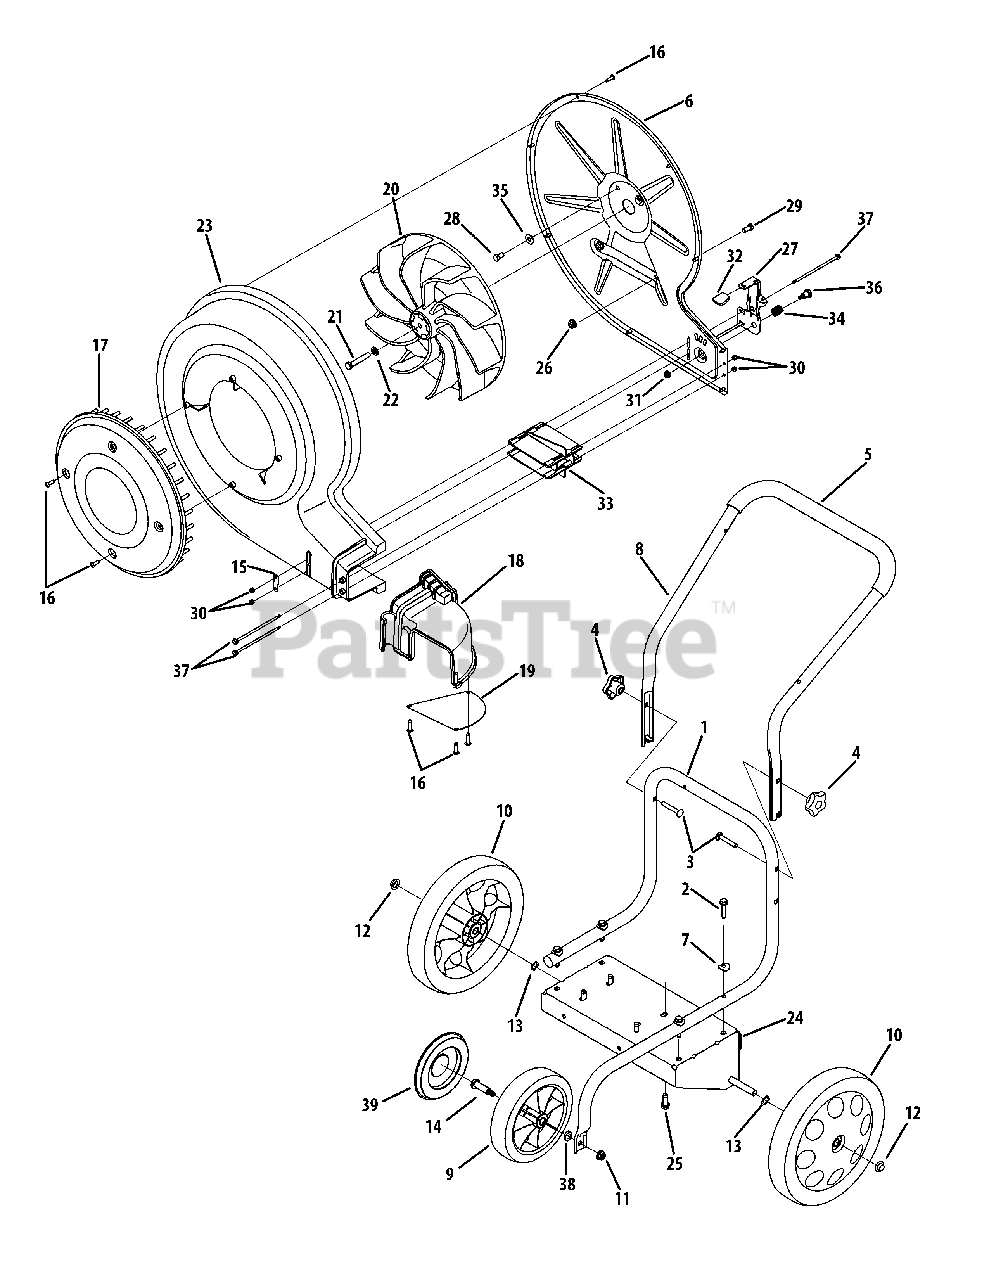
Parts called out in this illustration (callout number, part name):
1	Lower Handle Assembly
2	Hex Screw, 5/16-18 x 1.50
3	Carriage Screw, 5/16-18 x 2.00
4	Star Knob, 5/16-18
5	Foam Grip, .970 x 25
6	Back Plate
7	Saddle Washer, .320 x .93 x .060
9	Wheel, 8 x 2
10	Wheel, 12"
11	Flange Lock Nut, 3/8-16
12	Push Cap, 1/2"
13	Wave Washer, .510 x .750 x .017
14	Shoulder Screw, .496 x 1.605
16	Hex Screw, 12-16 x .75
17	Blower Cover
18	Chute Assembly
20	Impeler Assembly
21	Hex Screw, 3/8-24 x 2.25
22	Lock Washer, 3/8
23	Blower Housing
25	Sems Screw, 3/8-16 x 1.000
26	Flange Lock Nut, 5/16-18
28	Hex Bolt, 5/16-24 x .625
29	Hex Bolt, 5/16-18 x .75
30	Hex Lock Nut, #8-32
31	Flange Lock Nut, 1/4-20
32	Height Adjustment Knob
33	Louver Plate
34	Comp. Spring, .515 x .641 x .95
35	Bell Washer, .340 x .872 x .060
36	Shoulder Screw, .437 x .50 x 1/4-20
37	Shoulder Screw, .18 x 4.8 x 8-32
38	Flat Washer, .406 x .875 x .105
39	Hubcap, 8"
